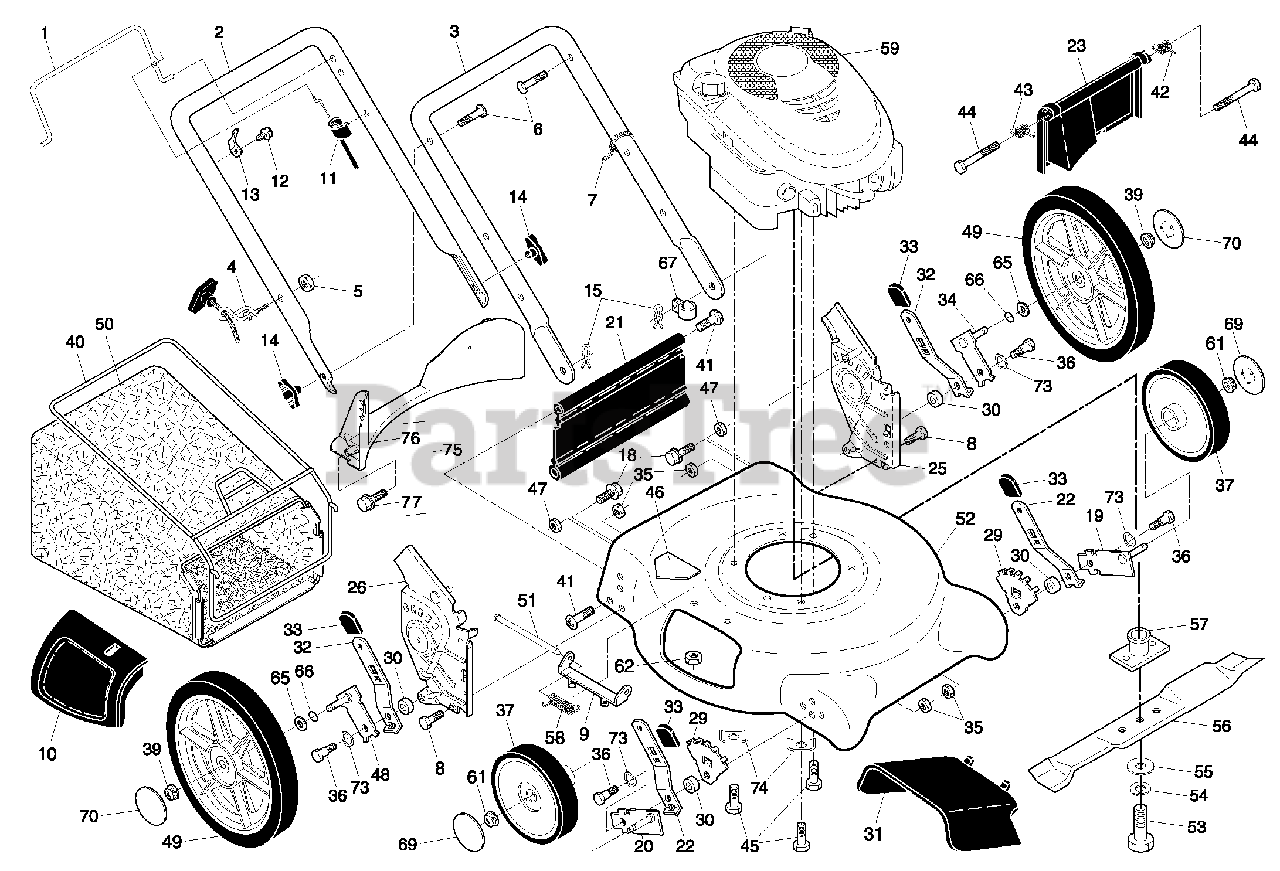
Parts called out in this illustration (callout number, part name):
1	Control Bar
2	Upper Handle
3	Lower Handle
4	Rope Guide
5	Locknut, Hex 1/4-20
6	Handle Bolt
7	Wire Tie
8	Hex Bolt 5/16-18 x 3/4
9	Mounting Bracket, Mulcher Door
10	Mulcher Door
11	Engine Zone Control Cable
12	Hex Washer Head Screw #10-24 x 1/2
13	Up-Stop Bracket
14	Handle Knob
15	Hairpin Cotter
18	Screw
19	Axle Arm Assembly, Front, LH
20	Axle Arm Assembly, Front, RH
21	Kit, Rear Skirt
22	Selector Spring, Front
23	Rear Door Assembly
25	Handle Bracket, LH
26	Handle Bracket, RH
29	Wheel Adjusting Bracket
30	Spacer
31	Deflector, Discharge
32	Selector Spring, Rear
33	Selector Knob
34	Axle Arm Assembly, Rear, LH
35	Locknut, Hex 5/16-18
36	Shoulder Bolt 5/16-18
37	Wheel & Tire Assembly, Front, 8"
39	Flanged Locknut
40	Frame, Grassbag
41	Hinge Screw
42	Spring, Rear Door, LH
43	Spring, Rear Door, RH
44	Bolt, Rear Door
45	Screw, Hex Head Thread Rolling Screw 3/8-16 x 1
46	Danger Decal
47	Nut, Hex
48	Axle Arm Assembly, Rear, RH
49	Wheel & Tire Assembly, Rear, 12"
51	Rod, Hinge
52	Kit, Lawn Mower Housing
53	Hex Head Screw, Grade 8, 3/8-24 x 1-3/8
54	Helical Lockwasher
55	Hardened Washer
56	21" Blade
57	Blade Adapter
58	Spring, Hinge Rod
61	Flanged Locknut
62	Nut, Hex
65	Washer, Flat 3/8
66	O-Ring
67	Clip, Cable
69	Hubcap, Front Wheel
70	Hubcap, Rear Wheel
73	Washer, Curved, Cylindrical
74	Washer, Special, Engine
75	Kit, Rear Baffle
76	Baffle, Rear
77	Screw, Rear Baffle
77	Operator's Manual, English
77	Operator's Manual, French
77	Repair Parts Manual
